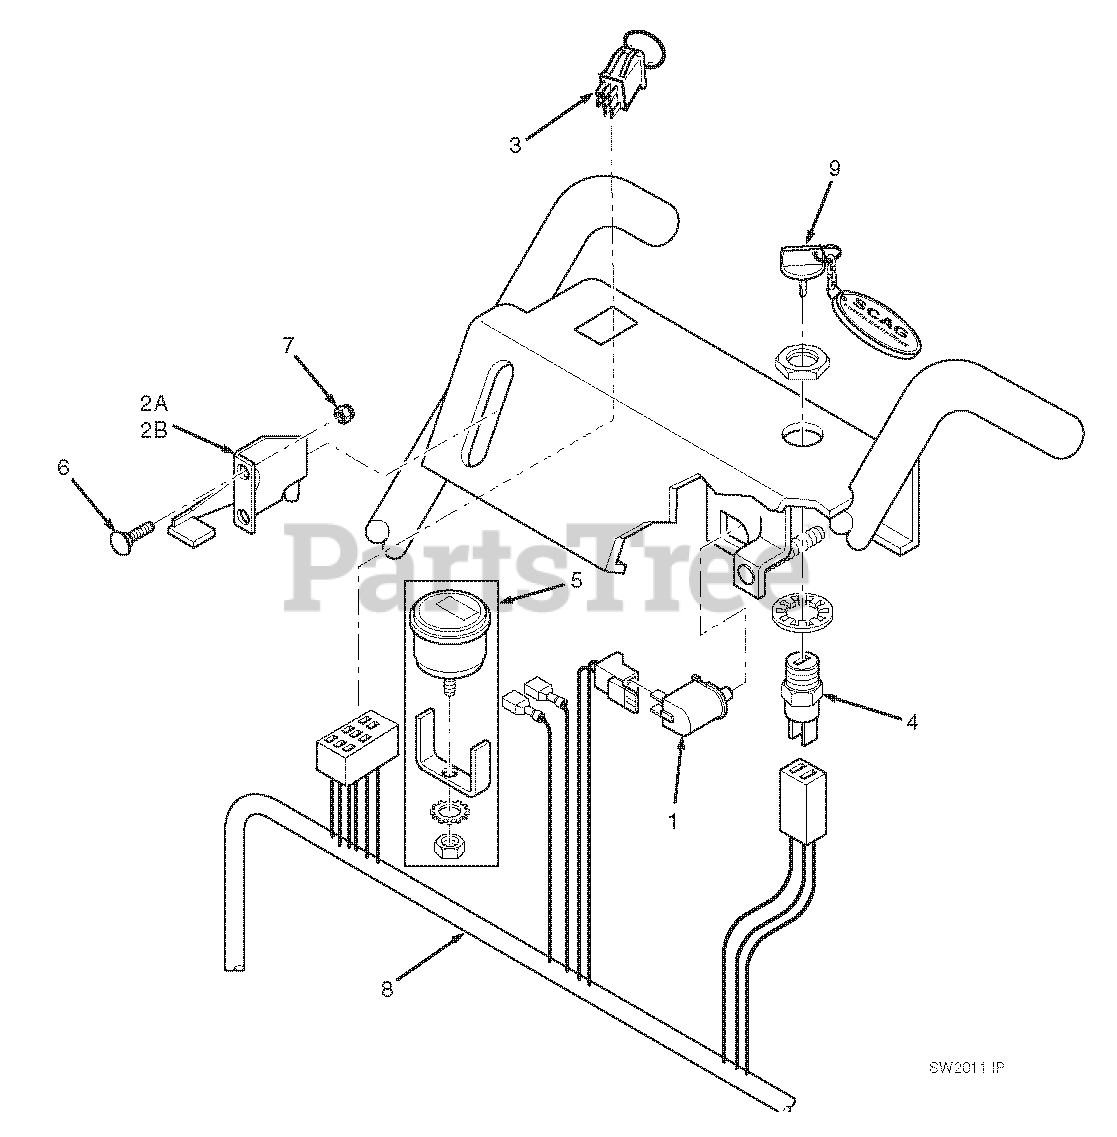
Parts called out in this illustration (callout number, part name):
1	Switch, Neutral Lock
2A	Throttle Contro
2B	Throttle Control
3	Engagement Switch, Electric Clutch
4	Key Switch
5	Hour Meter
6	Bolt, Carriage #10-32 x 1/2"
7	Nut, #10-32 Elastic Stop
8	Handle Wire Harness, Manual Start
9	Key Chain w/Keys
NS	Clamp, Wire Harness
